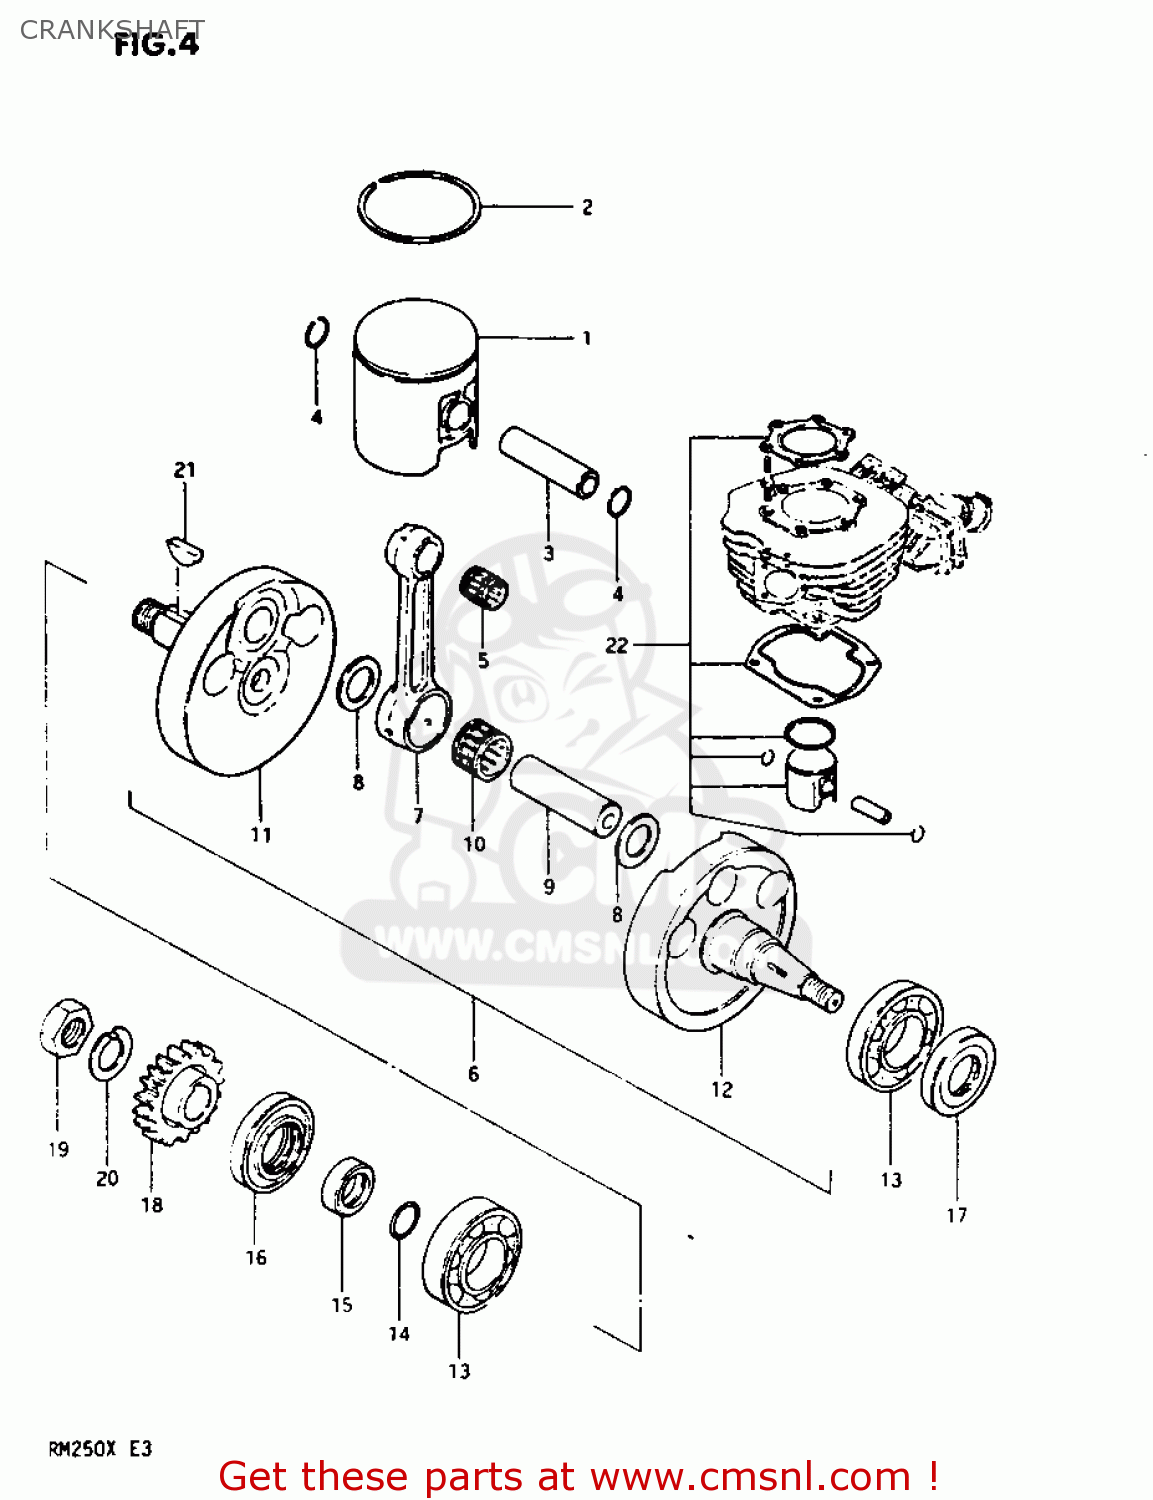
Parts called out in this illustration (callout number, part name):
1	PISTON (67.00MM)
2	RING,PISTON
3	PIN,PISTON (18MM)
4	CIRCLIP,PISTON PIN
5	BEARING(18X22X22)
6	CRANKSHAFT ASSEMBLY
7	ROD,CONNECTING
8	WASHER(24X29X1.5)
9	PIN,CRANK
10	BEARING
11	CRANKSHAFT
12	CRANKSHAFT,LEFT
13	BALL BEARING 30X62X16
14	O RING(D:2.4,ID:21.8)
15	SPACER,PRIMARY DRIVE GEAR
16	SEAL,OIL(36X52X8)
17	SEAL,OIL(19.6X37X8)
18	GEAR,PRIMARY DRIVE
19	NUT
20	WASHER
21	KEY
22	PISTON SET
